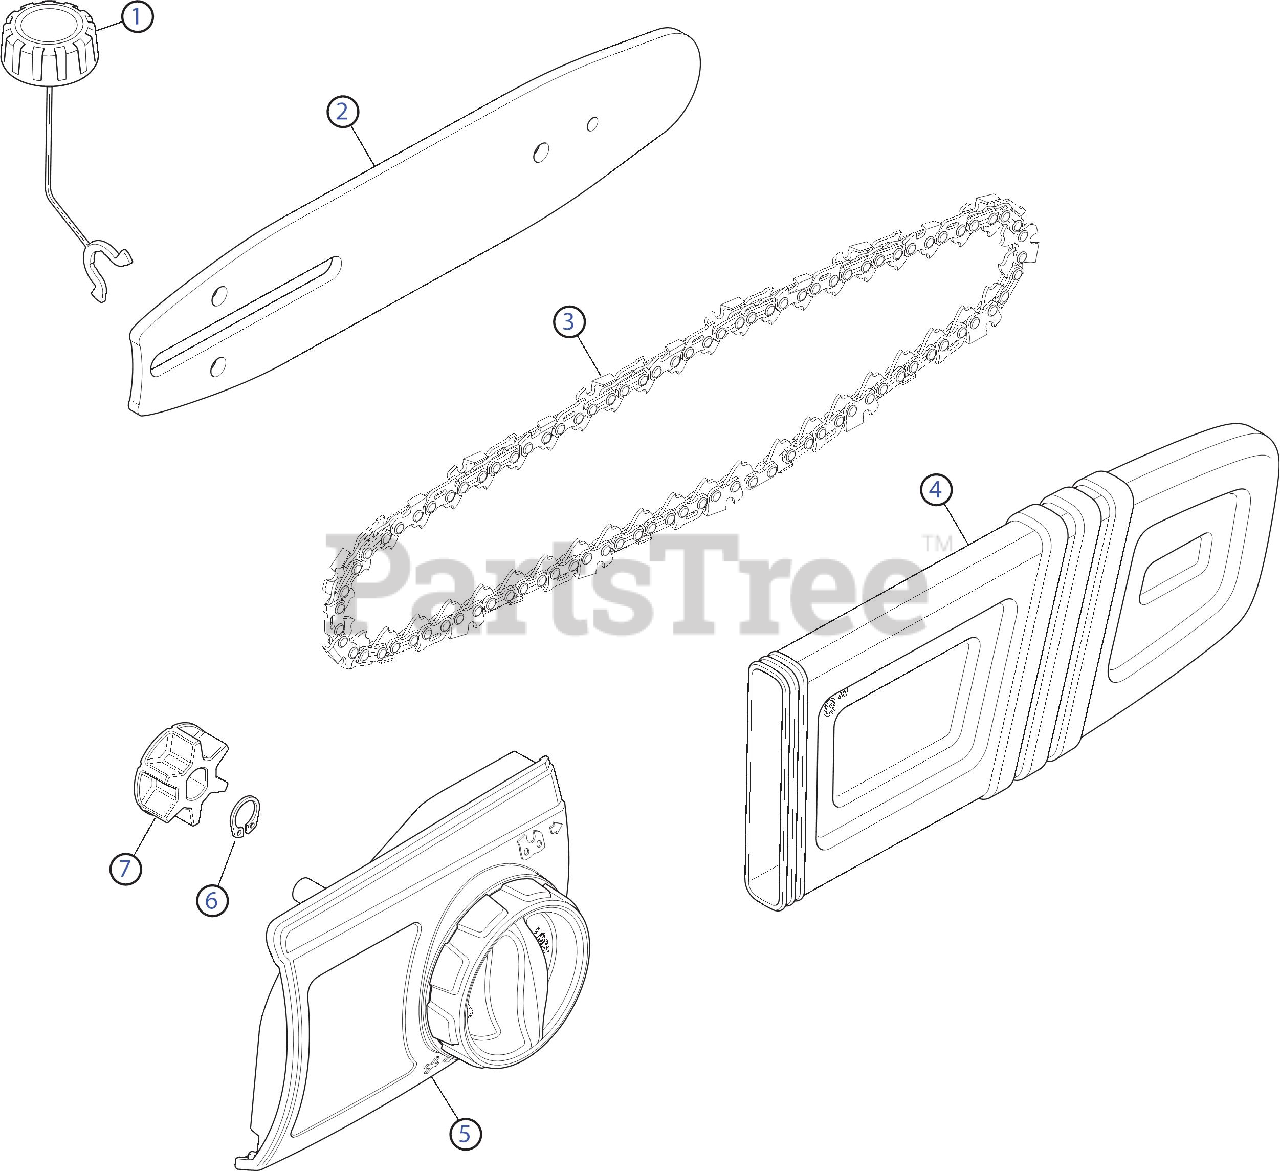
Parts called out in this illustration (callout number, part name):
1	Oil Cap Assembly
2	Guide Bar
3	Saw Chain
4	Scabbard
5	Drive Sprocket
7	Chain Tension / Bar Cover Assembly
